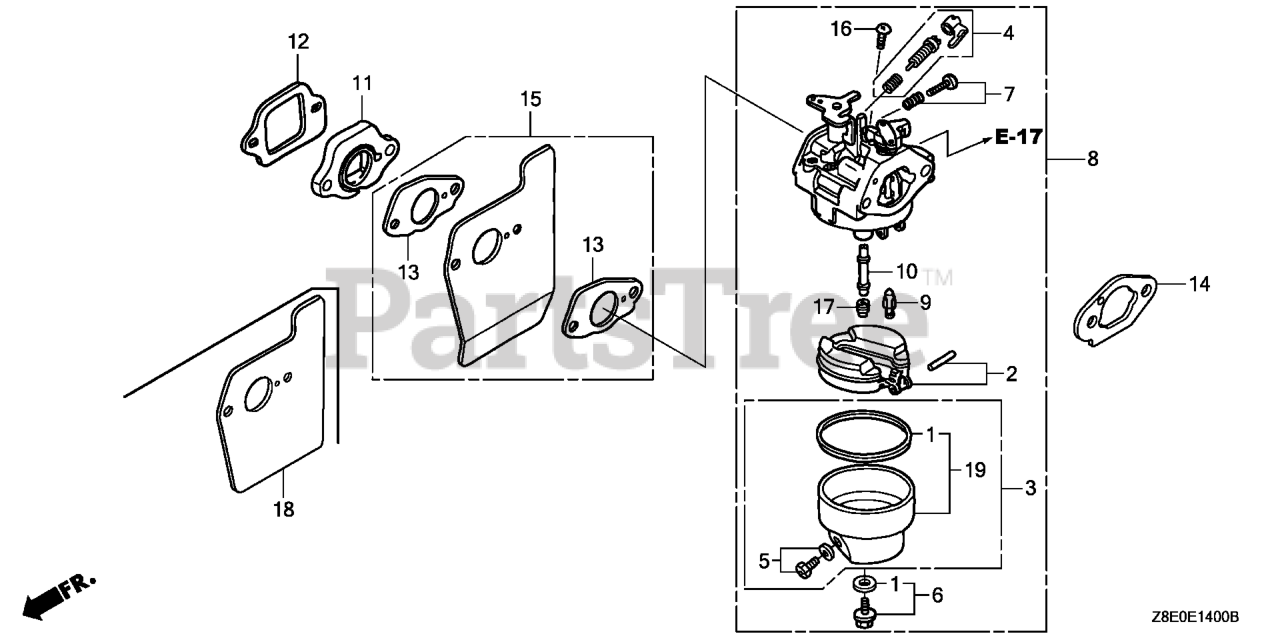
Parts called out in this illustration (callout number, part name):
1	GASKET SET
2	FLOAT SET
4	SCREW SET (CARBURETOR NO.)
6	SCREW SET B
6	SCREW SET
7	SCREW SET (THROTTLE STOP) (CARBURETOR NO.)
8	CARBURETOR (BB65W A)
9	VALVE, FLOAT (Honda Code 7934714). (CARBURETOR NO.)
10	NOZZLE, MAIN (CARBURETOR NO.)
10	NOZZLE, MAIN
11	INSULATOR, CARBURETOR
12	GASKET, INSULATOR
14	GASKET, CARBURETOR (Honda Code 5580253). (CHOKE SIDE)
16	SCREW, PAN (5X6)
17	JET, MAIN (#62) (Honda Code 0635482). (CARBURETOR NO.)
17	JET, MAIN (#65) Use up to Engine SN BB30A D.
17	JET, MAIN (#68) Use up to Engine SN BB30A D.
18	GUIDE, AIR
19	CHAMBER SET, FLOAT (CARBURETOR NO.)
